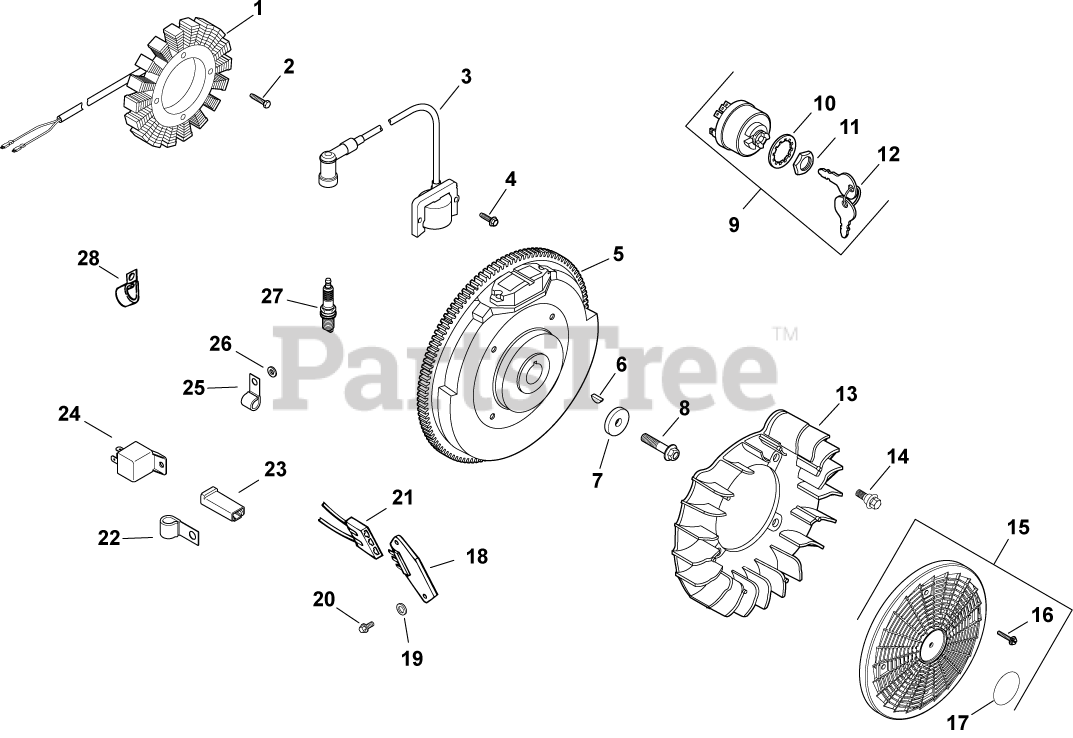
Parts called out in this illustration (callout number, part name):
1	KIT, 15 / 20 AMP STATOR
2	SCREW, M5X0.8X25 - (#25086402S)
3	KIT, MODULE IGNTN (CDI FIXED)
4	SCREW, FLG THD FRM M5X.8X20-(#25086399S)
5	FLYWHEEL, PAINTED-USE 24 025 55-S
6	KEY, 3/16" X 5/8"
7	WASHER, FLAT 13/32"
8	SCREW, FLG M10X1.5X45 - (#25086361S)
9	SWITCH ASSY, KEY (KM)-USE 25 099 32-S
10	WASHER, INTERNAL TOOTH
11	NUT, KEY SWITCH
12	KEY, SET -USE 48 340 01-S
13	FAN - USE (#24 157 11-S)
14	BOLT, SHOULDER
15	KIT, GRASS SCREEN
16	SCREW, FLG SEMS M4X.7X25
17	DECAL, GRASS SCREEN USE 24 113 499-S
18	REG/RECT-15 AMP (KM)-USE 41 403 10-S
19	WASHER, FLAT 7/32"
20	SCREW, PHL HD #11-16X7/8"
21	CONNECTOR, BODY (KM)-USE 25 155 41-S
22	CLIP, CABLE
23	CONNECTOR (1 CONTACT)
25	CLIP, CABLE
26	WASHER, FLAT 1/4" (O.D. 1/2")
27	PLUG, SPARK (PRO SERIES)
28	CLIP, TUBE & WIRING (KM)
